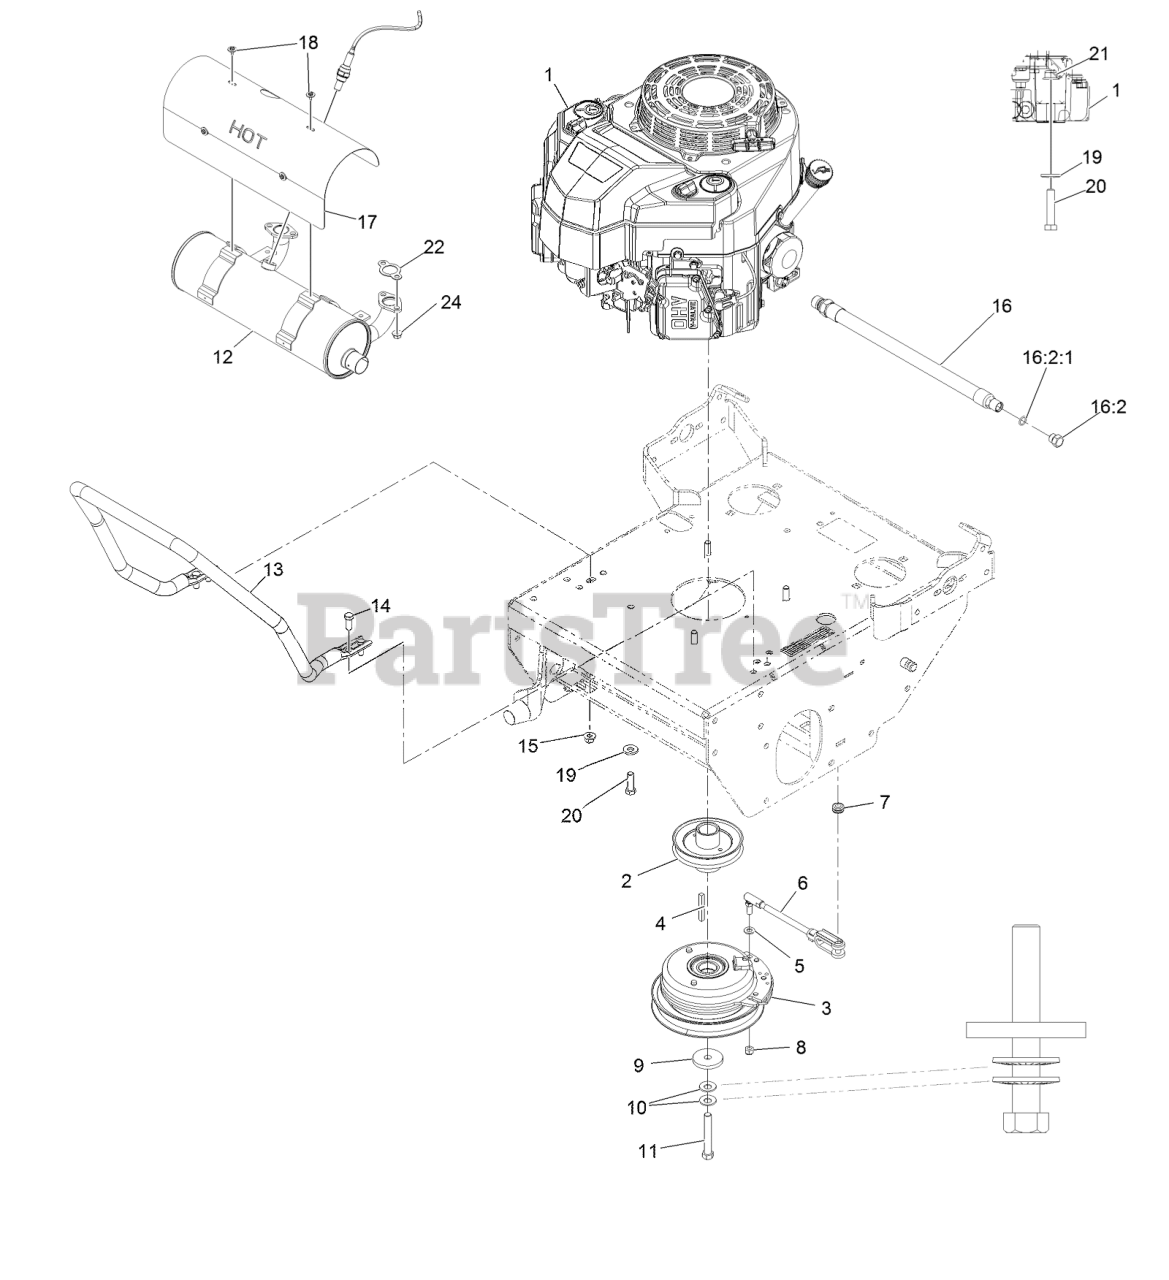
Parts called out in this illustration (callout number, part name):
2	SHEAVE, W/ HUB
3	CLUTCH, 125 FT/LBS, 1.13
4	KEY-SQUARE
5	WASHER-PLAIN
6	ASM, CLUTCH ANCHOR
7	GROMMET
8	NUT-LOCK
9	WASHER-CLUTCH
10	WASHER-SPRING
11	SCREW-HH
12	MUFFLER-TTX, EFI
13	Guard,Air Cleaner
14	SCREW-HH
15	NUT-HF, NI
16	OIL DRAIN HOSE ASM
16:2	PLUG-HH
16:2:1	O-RING
17	SHIELD-MUFFLER,TTX EFI
18	SCREW-HH, THREAD FORMING
19	WASHER-SPRING
20	SCREW-HH
21	NUT-HF, NI
22	GASKET-EXHAUST
24	NUT-FLANGE
